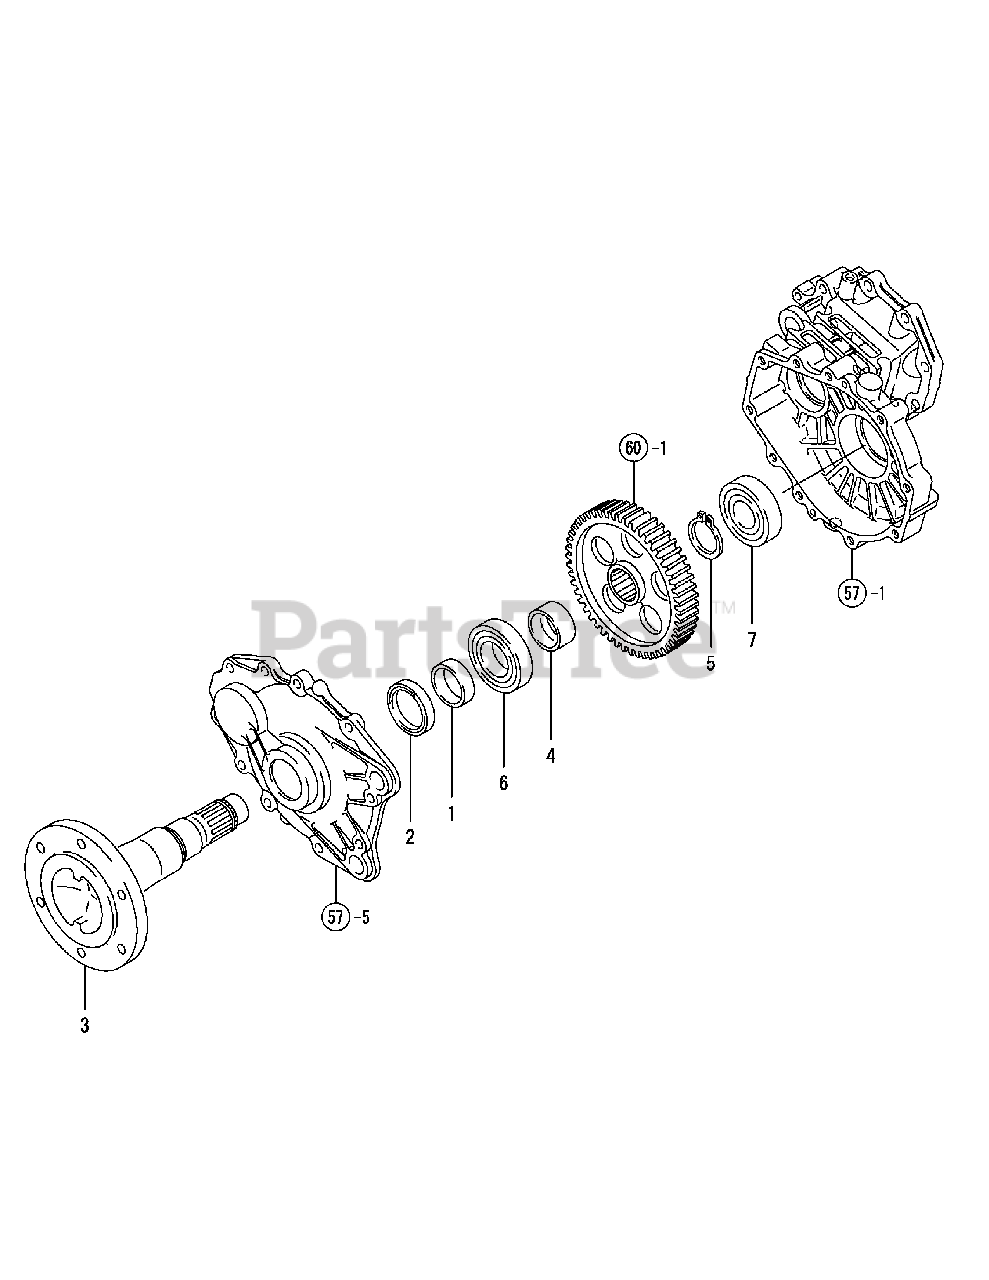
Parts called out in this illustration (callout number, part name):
1	Sleeve Si455016
2	Seal Tc6Y 506812.5
3	Shaft, Rear Axle
